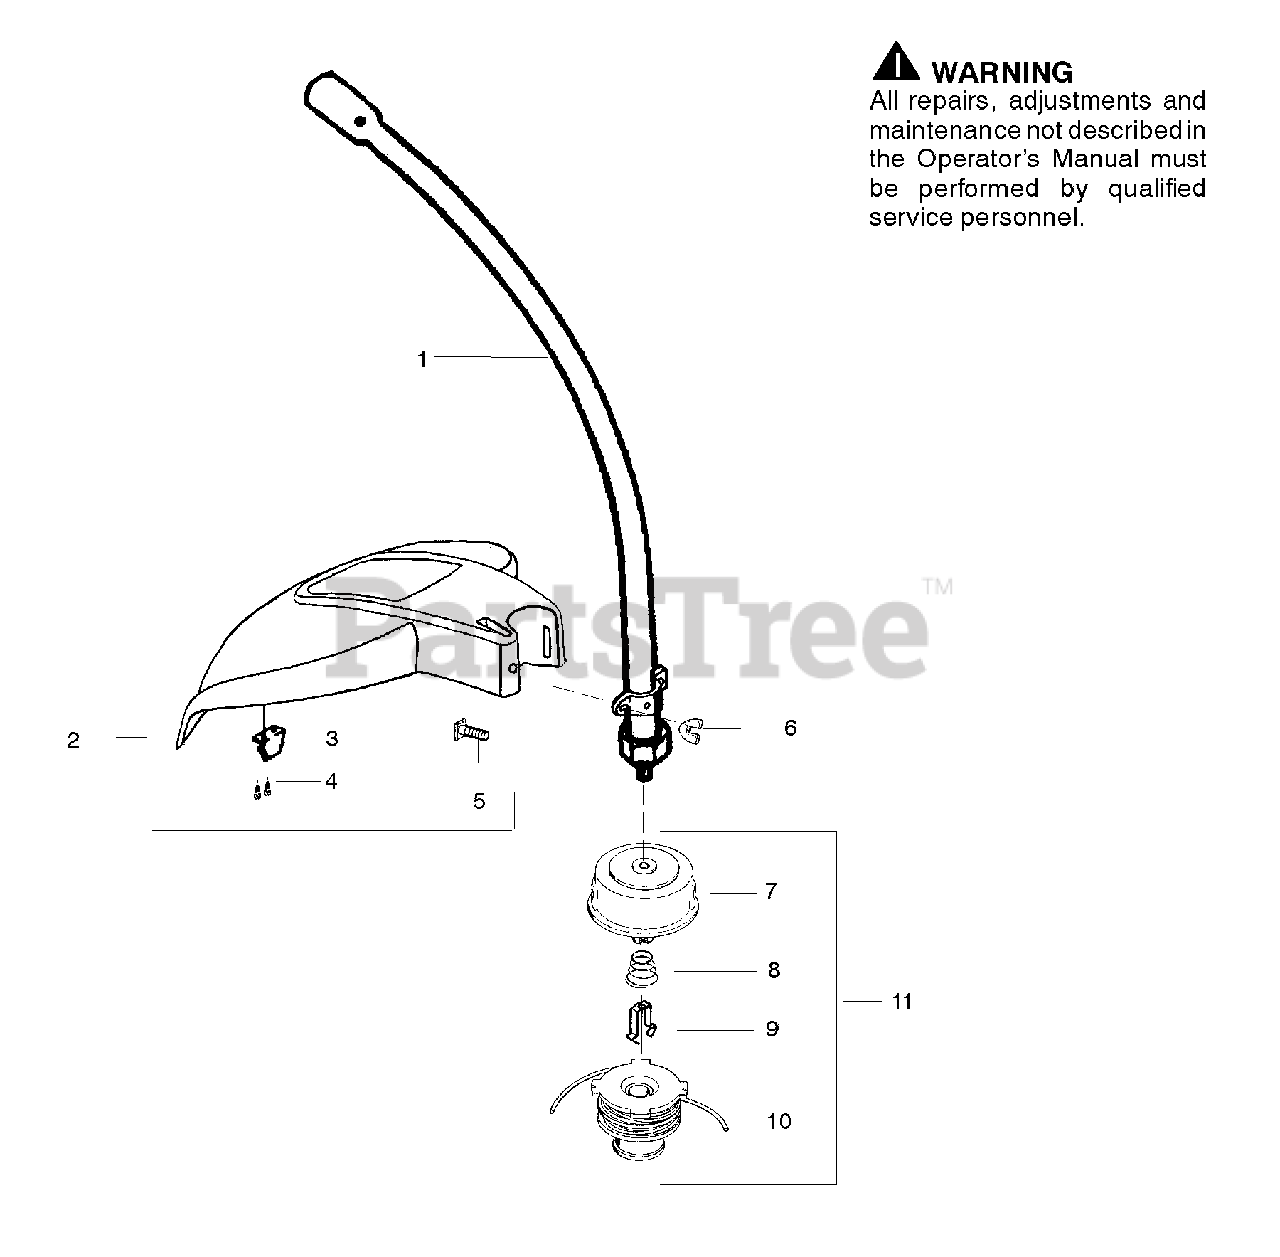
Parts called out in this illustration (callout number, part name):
1	Kit-Lower Shaft Assy.
2	Kit-Shield Assy.
3	Limiter-Line
6	Wingnut
7	Assy-Hub/Arbor
8	Spring-Return
9	Retainer-Spool
10	Accy-Wound Spool
11	Accy-Cutting Head
